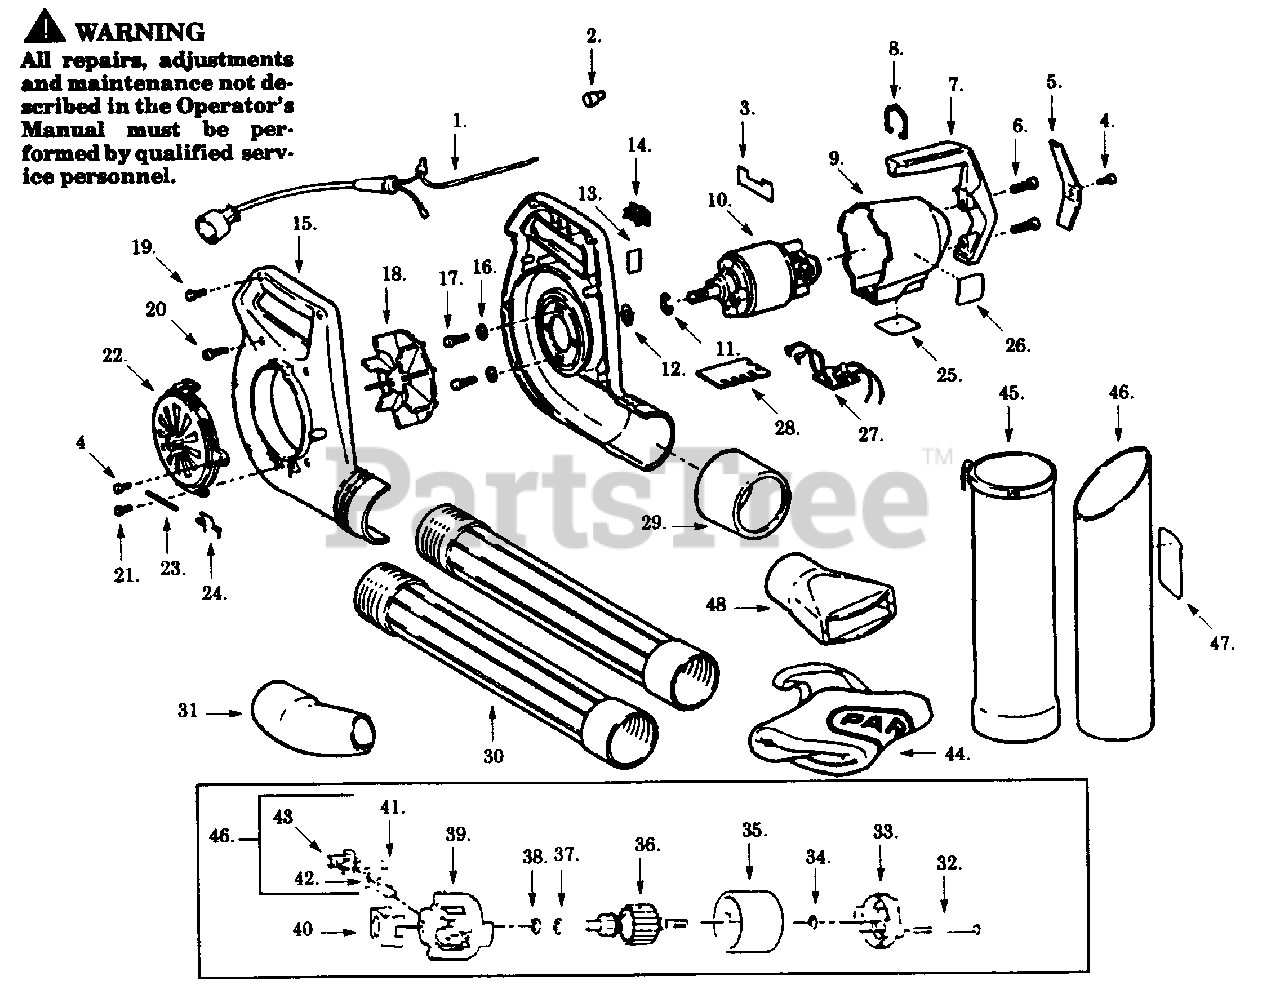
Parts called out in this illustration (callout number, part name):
1	Power Cord Ass'y.
2	Wire Nut
3	Switch Label
7	Side Handle
9	Motor Cover
10	Motor Ass'y.
11	Retaining Ring
13	Hsg. Front Label (Not a serviceable part)
14	On/Off Switch
15	Housing Set
18	Impeller Ass'y.
22	Inlet Cover Ass'y.
23	Pin Hinge
24	Return Spring
25	Warning Label
26	Motor Cover Label (Not a serviceable part)
27	P.C. Board Ass'y.
28	Mounting Board
29	Ferrule Sleeve
30	Outlet Tube
33	Endbell Ass'y. (Drive)
35	Field Ass'y.
36	Armature Ass'y.
39	Endbell Ass'y. (Brush)
40	Insulator
42	Brush Spring
43	Brush Holder
44	Vacuum Bag
45	Vacuum Tube
46	Brush Kit (Incl.41,42,43)
47	Warning Label-Tube
48	Diffuser Nozzle
